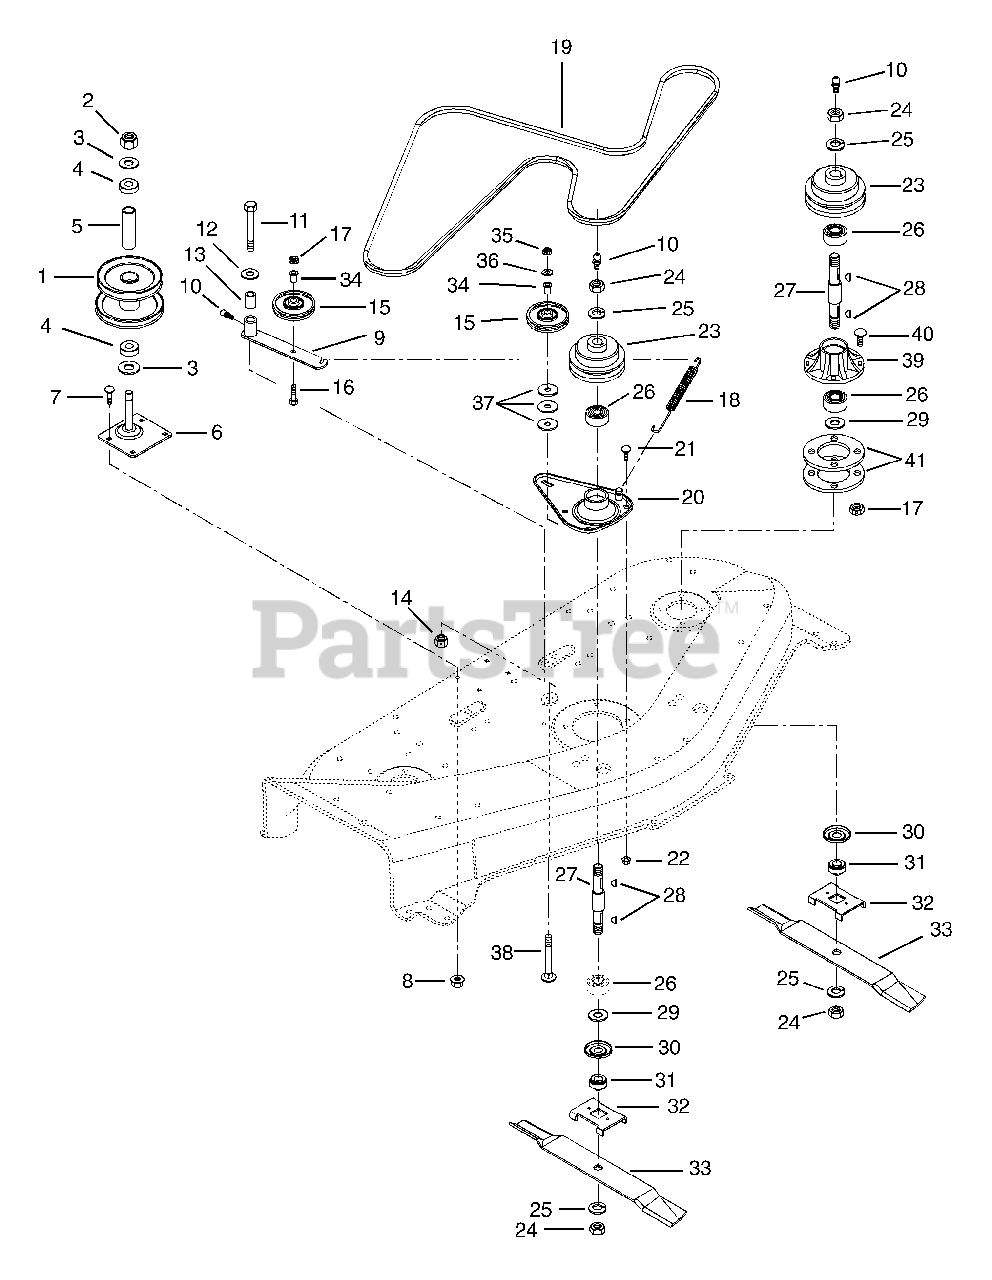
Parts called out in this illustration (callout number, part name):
1	JACKSHAFT - 48" DECK
2	@NUT-LK-NYL .625-18 YWZC
3	WSHR-FL-STL .630X1.005X.062 YZ
4	BRG-BALL .625X1.375X.44
5	SPACER .640X.880X2.545
6	PLATE - MOUNT
7	@BLT-RHDSSQNK .31-18X.62 G5YZ
8	@NUT-SPNLK-FLG .312-18 YWZC
9	ARM - IDLER
10	FTG-LUBE .25-28X.256 YWZC
11	@BLT-HEX .50-13X2.75 GR5 YWZC
12	WSHR-FL-STL .505X.880X.072 YWZ
13	SPACER, PIVOT .500X.750X1.805
14	@NUT-LK-CTR .50-13 YWZC
15	IDLER, PLASTIC, 4.00 X .50 ID
16	@BLT-HEX .38-16X1.25 GR5 YWZC
17	@NUT-LK-CTR-JAM .375-16 YWZC
18	SG-TENS .075X.75X2.25 WLD20.7
19	V-BELT, HA-RAW EDGE
20	HOUSING, SPINDLE
21	@BLT-RDHDSQNK .38-16X.75 G2YWZ
22	@NUT-LK-CTR .38-16 YWZC
24	NUT-JAM .75-10 YWZC
25	@WSHR-LK .75X.188 REG YWZC
26	BRG-BALL .750X1.781X.61
27	SPINDLE SHAFT W/ZERK
28	KEY-WDRF .188X.625X.25 SAE 61
29	WSHR-FL-STL .754X1.000X.032 YZ
30	BEARING SLINGER
31	RETAINER HUB
32	BLADE TRAY 48
34	SPACER -FLANGED .390X.500X.781
35	@NUT-LK-CTR .38-16 YWZC
36	@WSHR-FL-STL.38X.875X.083 YWZC
37	WSHR-FL-STL .390X1.5X.125 YWZC
38	@BLT-RDHDSQNK .38-16X2.00 G2YZ
39	SPINDLE HOUSING
40	@BLT-RDHDSQNK .38-16X.75 G2YWZ
41	SPACER, SPINDLE
